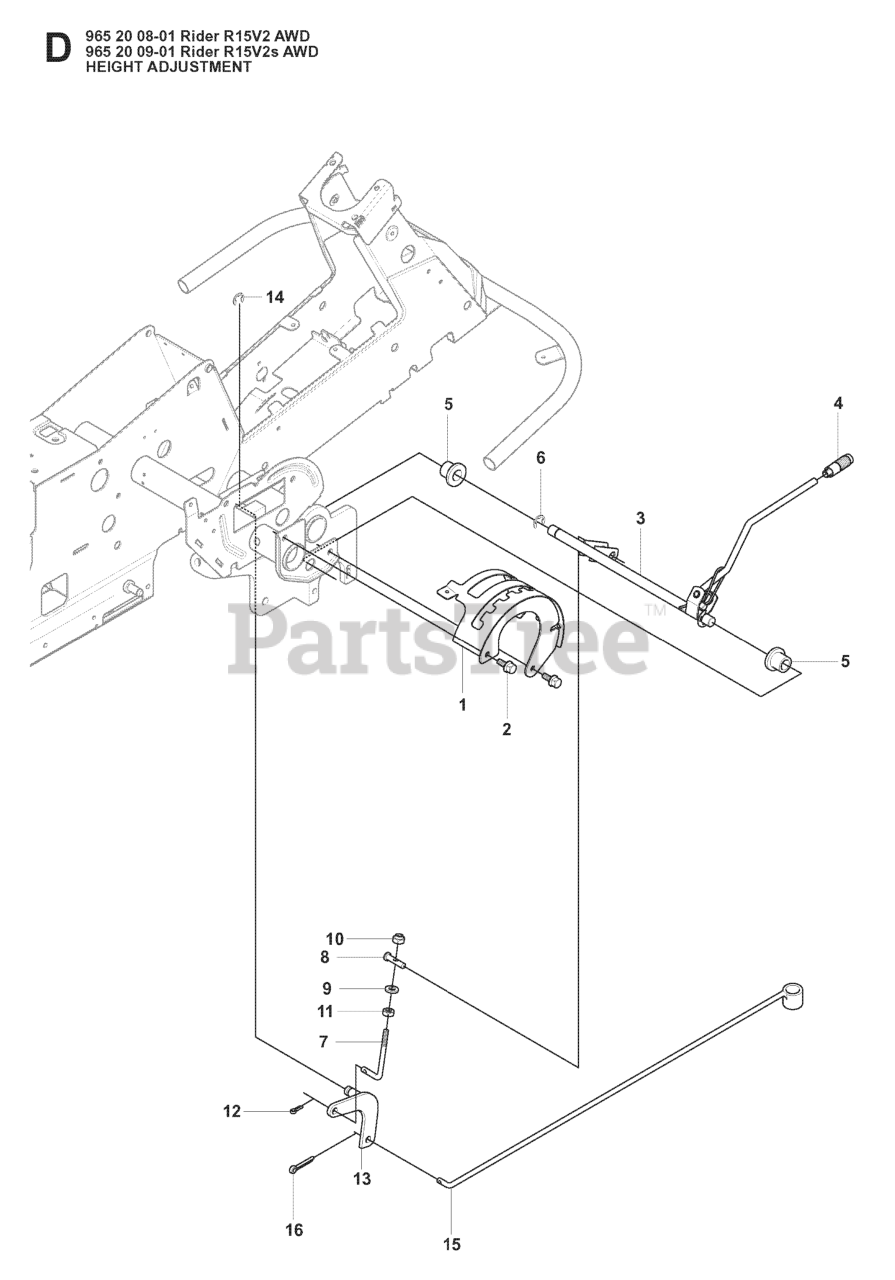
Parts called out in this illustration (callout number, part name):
1	CONTROL PLATE
3	HEIGHT ADJUSTER
4	GEAR STICK KNOB
5	BUSHING
9	WASHER
10	LOCKNUT M8
11	NUT
14	RETAINING RING
15	CLUTCH ROD
